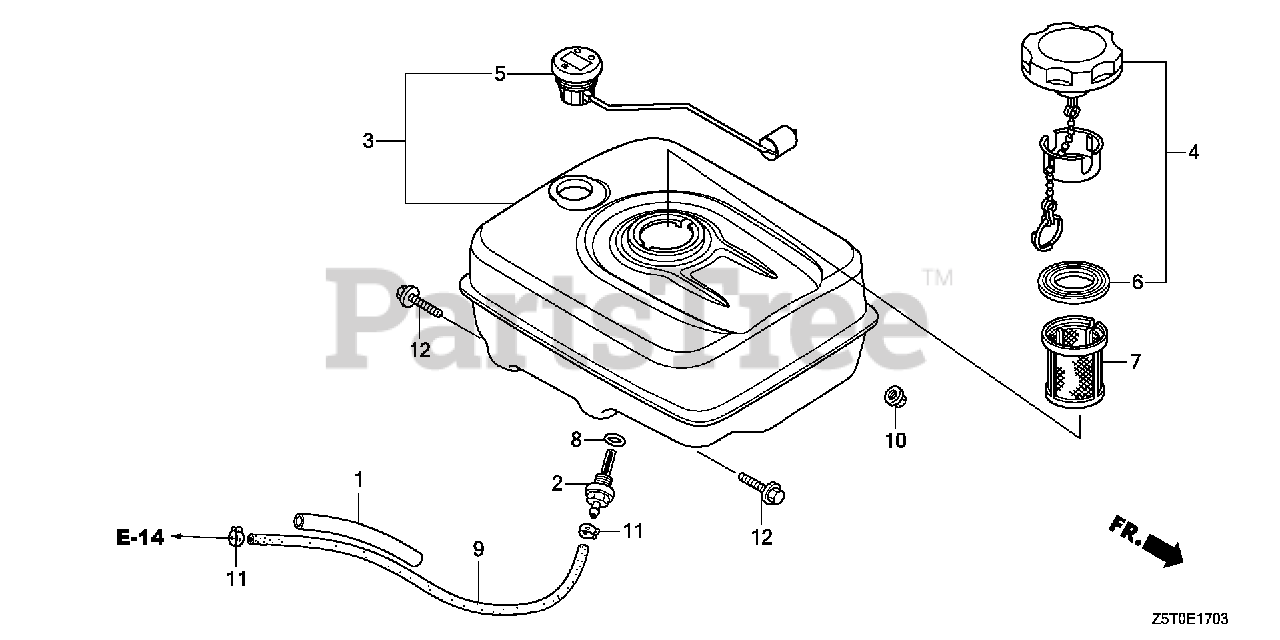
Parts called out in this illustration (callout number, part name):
1	RUBBER, SUPPORTER (107MM)
2	JOINT, FUEL TANK
3	TANK ASSY., FUEL *NH1* (GAUGE) (BLACK)
4	CAP, FUEL FILLER
5	GAUGE ASSY., FUEL
6	GASKET, FUEL FILLER CAP
7	FILTER, FUEL (FROM 1204807)
8	O-RING (14MM) (ARAI) Use up to Engine SN 2949254.
8	O-RING (14MM) (NOK)
9	TUBE, FUEL (4.5X235) (FKM)
10	NUT, FLANGE (8MM)
11	CLIP, TUBE (D8)
12	BOLT, FLANGE (8X25)
